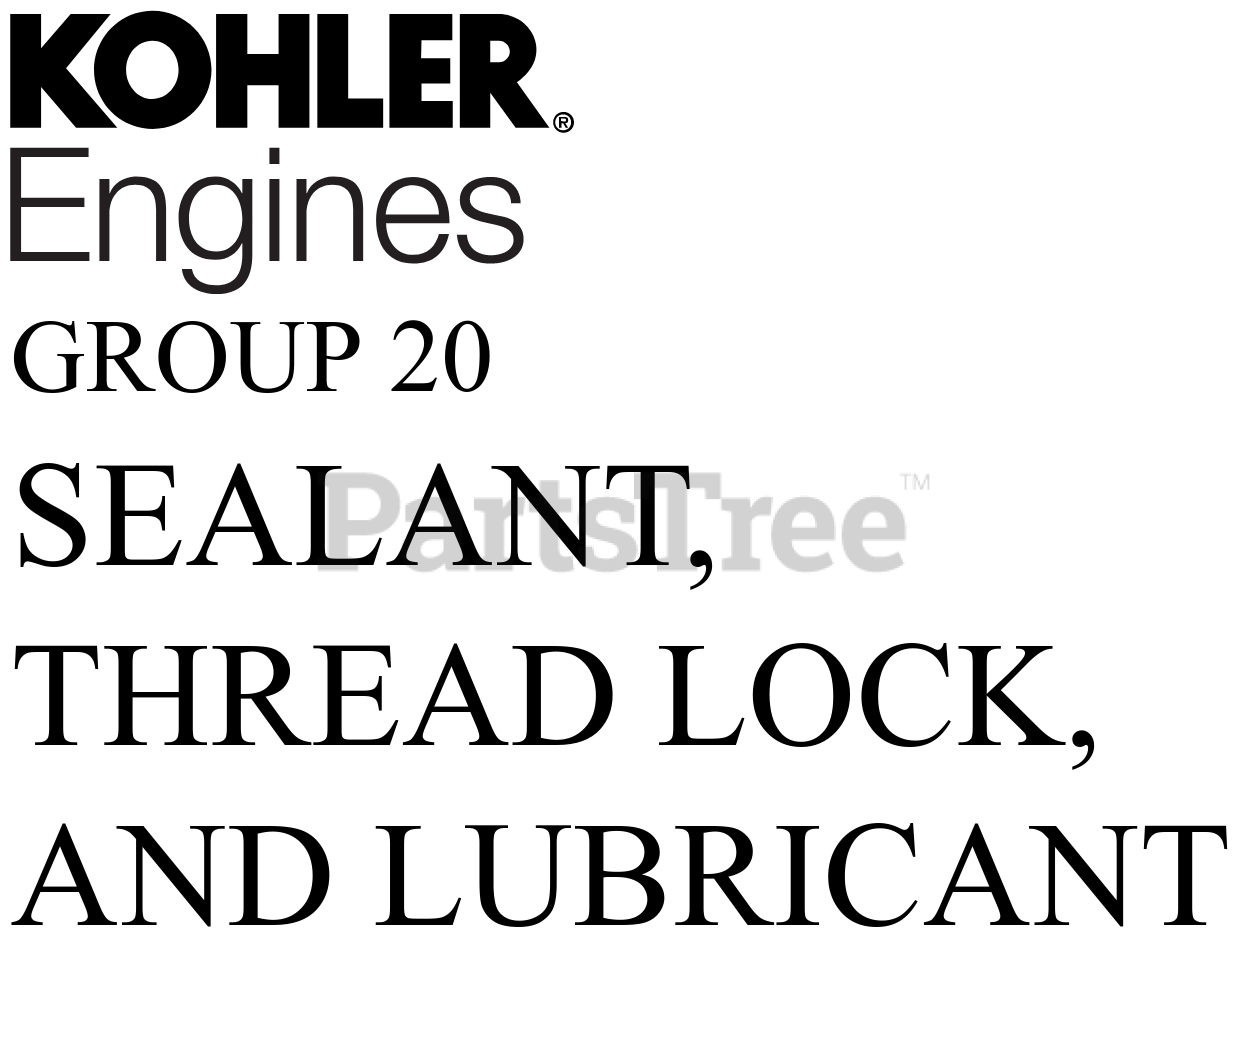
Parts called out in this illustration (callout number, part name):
NI	QUART OF OIL - SAE30
NI	QUART OF OIL - 10W30-USE 25 357 65-S
NI	LUBRICANT, GREASE (SPLINE)
NI	LUBRICANT, CAMSHAFT
NI	20W50 OIL (QUART)-USE 25 357 68-S
NI	SEALANT(LOCTITE 620)-(#2559711S)
NI	SEALANT(LOCTITE 222 RETAIN CMPND 0.5ML)
NI	SEALANT(LOCTITE INSTANT GASKET 4 OZ)
NI	LUBRICANT, BENDIX STARTR
